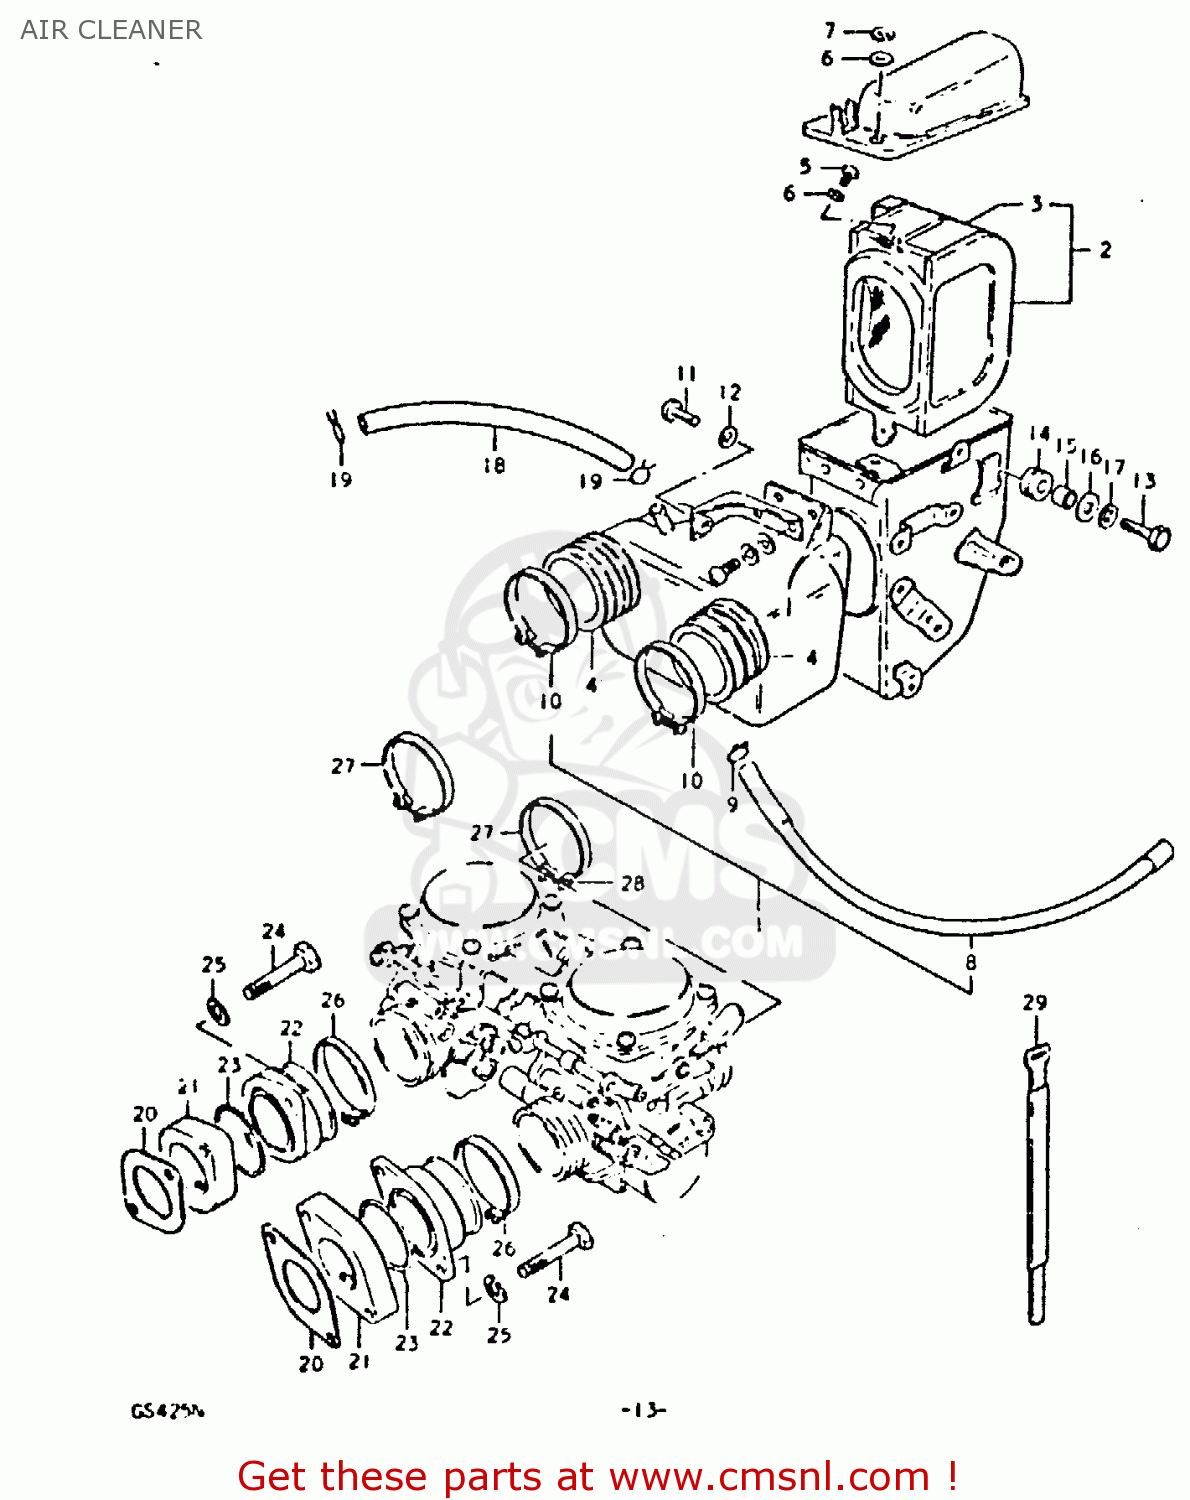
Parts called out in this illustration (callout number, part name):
1	CLEANER ASSEMBLY,AIR
2	FILTER ASSY
3	FILTER
4	HOSE,AIR CLEANER INLET
5	SCREW
6	WASHER
7	LOCK WASHER
8	HOLDER,FILTER
9	HOSE,AIR CLEANER
10	CLAMP
11	SCREW
12	WASHER 6MM
13	BOLT
14	CUSHION
15	SPACER (6.1X9X9)
16	WASHER
17	LOCK WASHER
18	HOSE
19	CLIP
20	GASKET,CARBURETOR (NAS)
21	INSULATOR,CARBURETOR
22	PIPE,INTAKE
23	O-RING (D:2.4 ID:39.7)
24	BOLT
25	LOCK WASHER
26	CLAMP
27	CLAMP
28	SCREW
29	CLAMP
